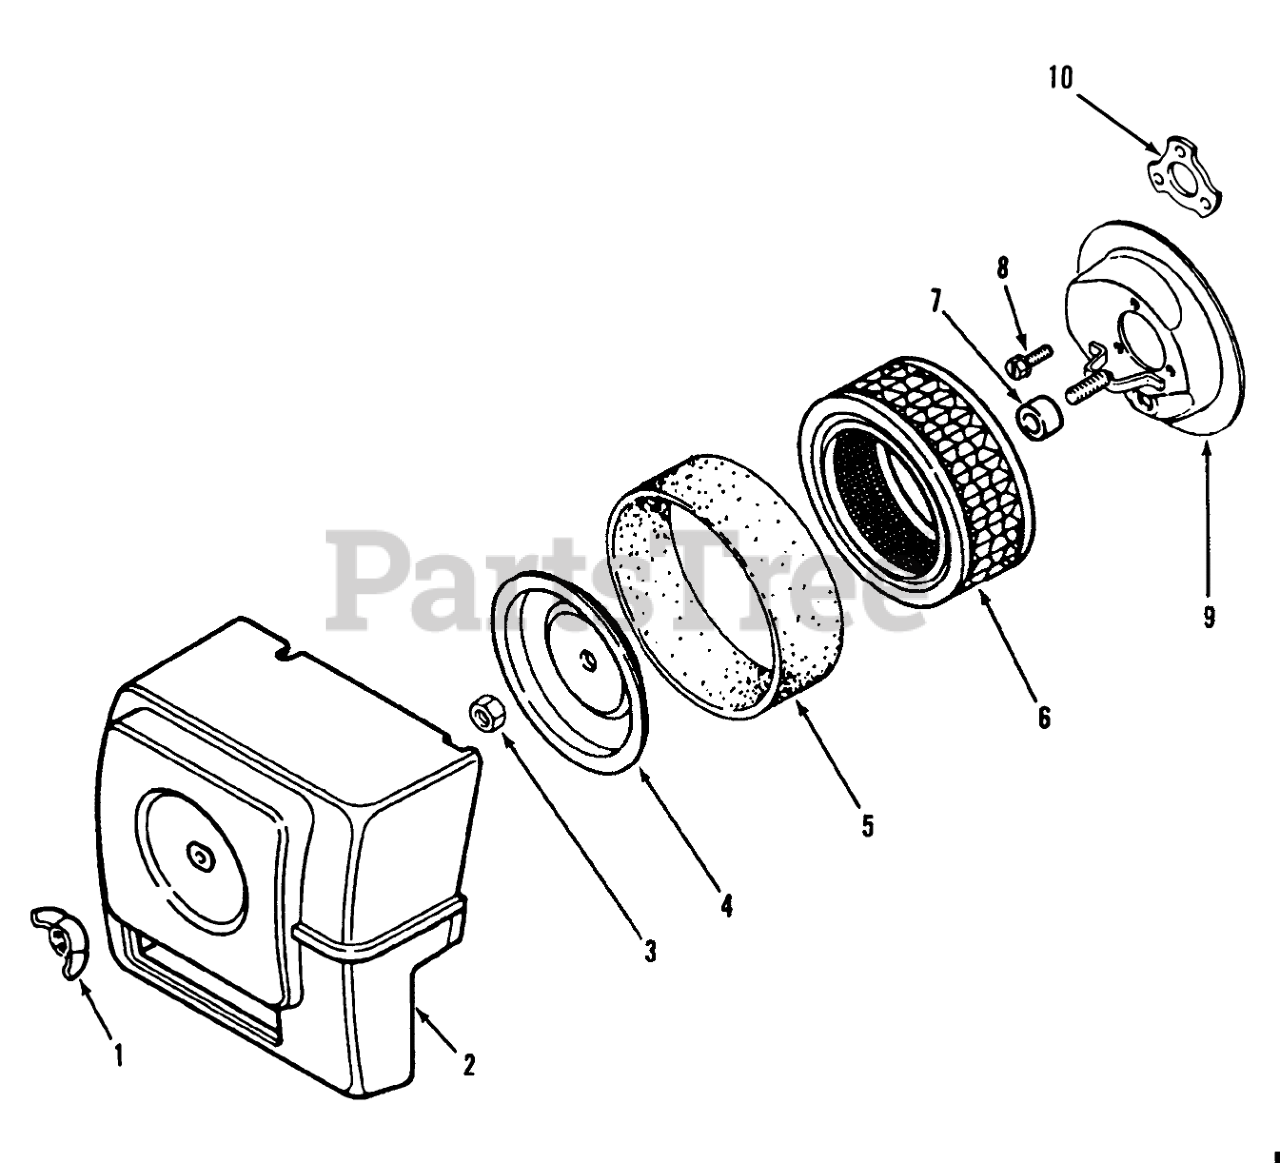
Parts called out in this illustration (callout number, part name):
1	Nut-Wing
2	Cover
4	Air Cleaner Element Cover
5	Element-Precleaner
6	Element
8	Screw
9	Base-AirCleaner
10	AirHornGasket
